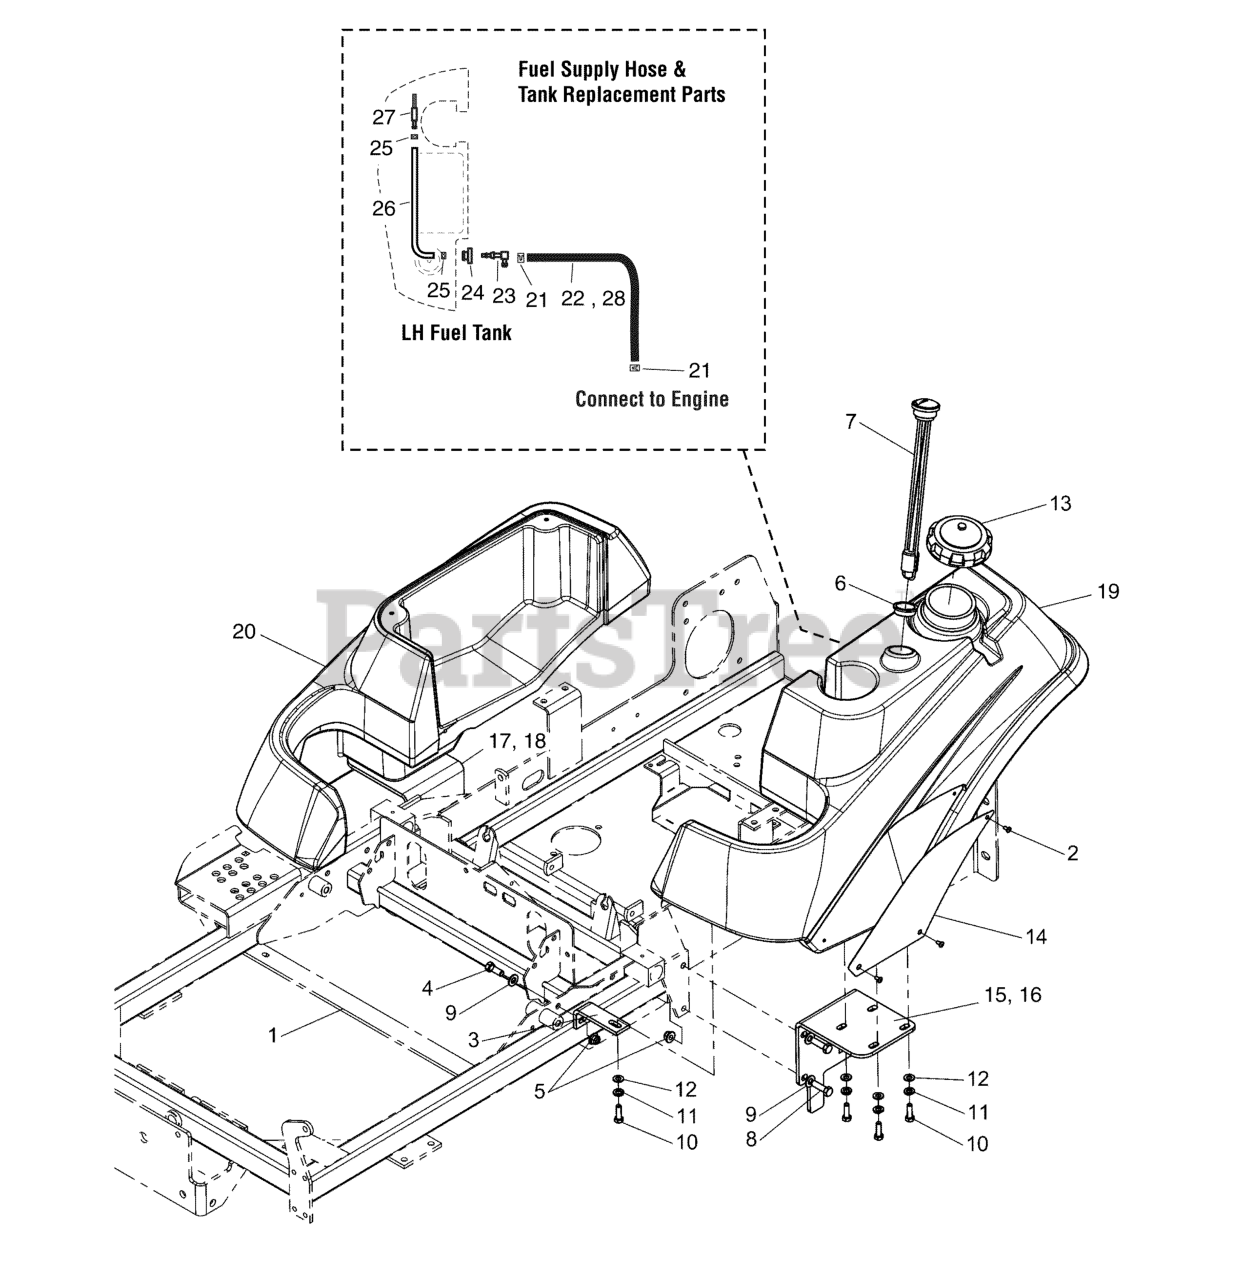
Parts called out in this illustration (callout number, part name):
1	MAIN FRAME
2	SCREW, Allen Head, #10-24 x 3/8"
3	*MOUNT, TANK, FRONT - BLK
4	BOLT, 3/8-16 X 1" GD5 CZ
5	NUT, 3/8-16 Hex Nylock Flange
6	GROMMET
7	GAUGE, FUEL, 12
8	BOLT, 3/8-16 X 1-1/4" GD5 CZ
9	WASHER 3/8" GD.9 FLAT
10	BOLT, 5/16-18 X 1"
11	WASHER, 5/16 LOCK CZ
12	WASHER, 5/16" GD.9 FLAT
14	PLATE, BADGE
15	WELD, TANK MOUNT, LH - BLK
16	WELD, TANK MOUNT, LH - BLK
17	WELD, TANK MOUNT, RH - BLK
18	WELD, TANK MOUNT, RH -BLK
20	TANK, FENDER, IS1500Z/IS500Z - RH
21	CLAMP, HOSE EXTERNAL, 1/2 - RED
22	HOSE, 1/4" FUEL, 4.00"
24	BUSHING-FUEL TANK RED RUBBER
26	HOSE ASSEMBLY
28	HOSE, 1/4" FUEL, 6" LONG
